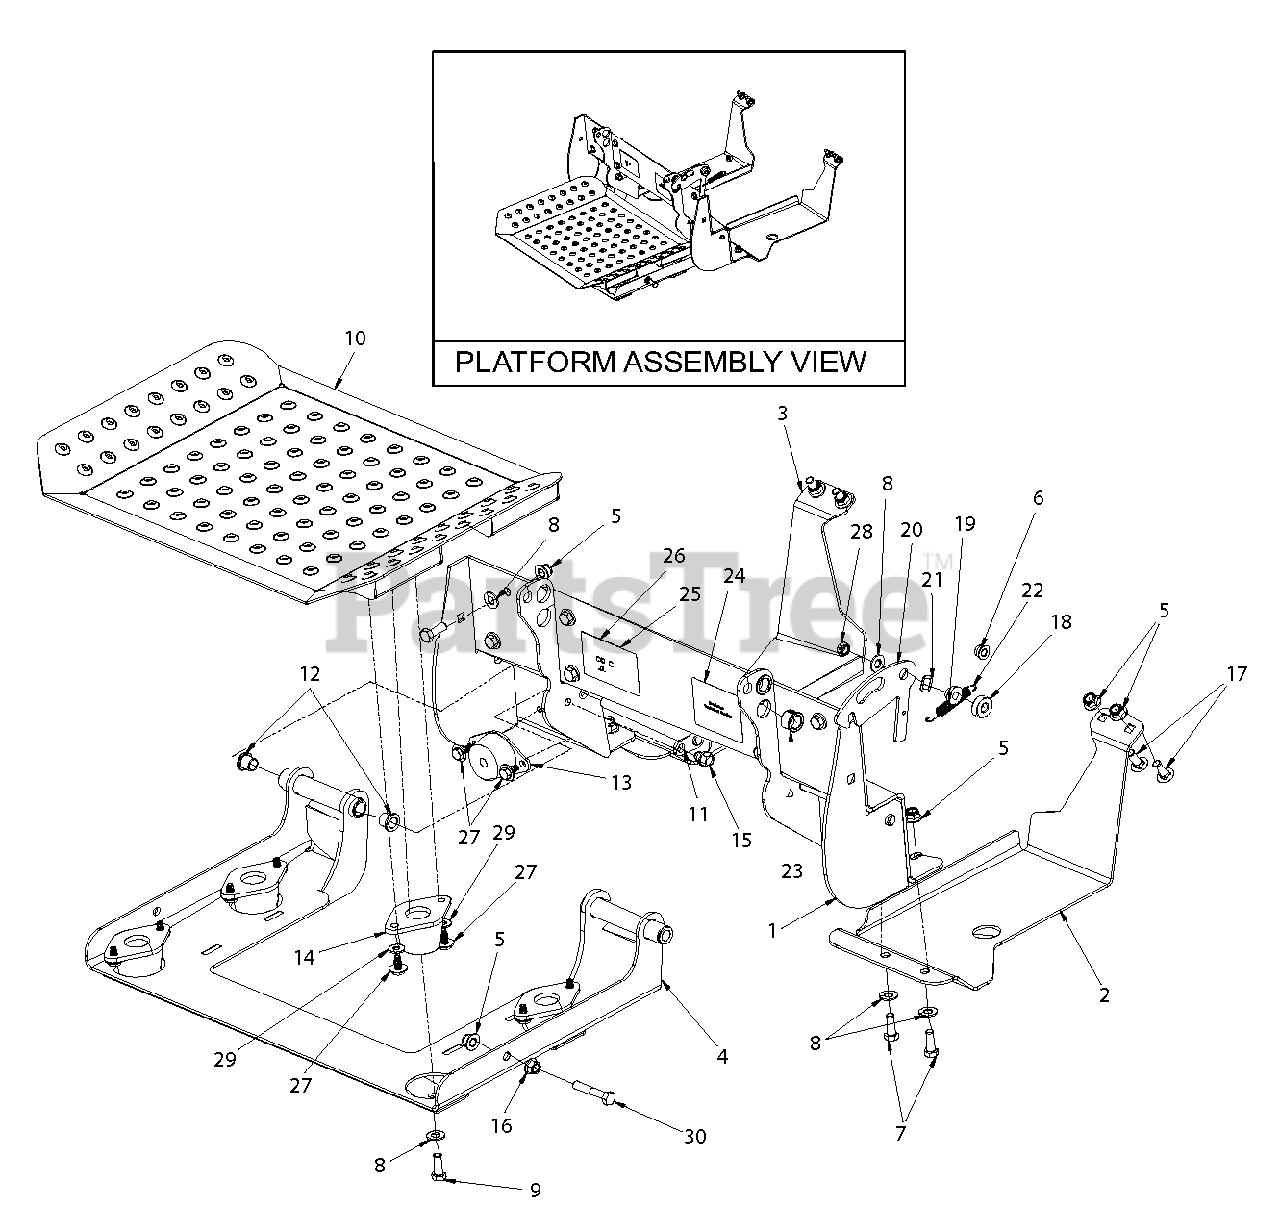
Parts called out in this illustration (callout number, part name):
1	WLDMT, PLATFORM SUPPORT
2	PLATE, TRANS SKID RH
3	PLATE TRANS SKID LH
4	WLDMT PLATFORM CARRIER
5	NUT, LOCK NYLOC FLANGE .38-16 YWZC
6	NUT, LOCK NYLOC FLANGE .31-18 YWZC
7	BOLT, HEX .38-16 X 1.00 GR4 YWZC
8	WASHER FLAT STL .406 X .812 X .065 YWZ
9	BOLT, HEX .38-16 X 1.00 GR5 YWZC
10	WLDMT, PLATFORM TOP
11	WLDMT PIN AND LOCK
12	BRG, FLG .500 X .625 X .500 BRNZ
13	MOUNT, ENGINE VIBRATION ISO
14	MOUNT, ISOLATOR
15	SCR TAP .38-16 X .50 HWH TR YWZ
16	NUT SPNLK FLG .375-16 YWZC
17	BOLT RKHDSQNK .38-16 X 1.00 GR5 YWZC
18	SPCR .375 X 1.00 .342
19	BSH, FLG .385 X .500 X .875 X .406
20	LATCH, PLATFORM SIDE
21	WAVE WASHER .531 X .781 X .125 FH
22	SPRG, EXTENSION
23	BUSH, PANEL SNAP .687 X .875 X .56
24	DECAL, HYDRO BELT (PROSTANCE)
25	FORM PRODUCT ID
26	OVERLAMINATE
27	BOLT 5/16-18 X .625 SLF TAP FLG
28	NUT LK CTR .375-16 YWZC
29	WSHR FL STL .312 X .734 X .065 YWZ
30	BOLT, HEX .38-16 X 2.00 GR5 YWZC
